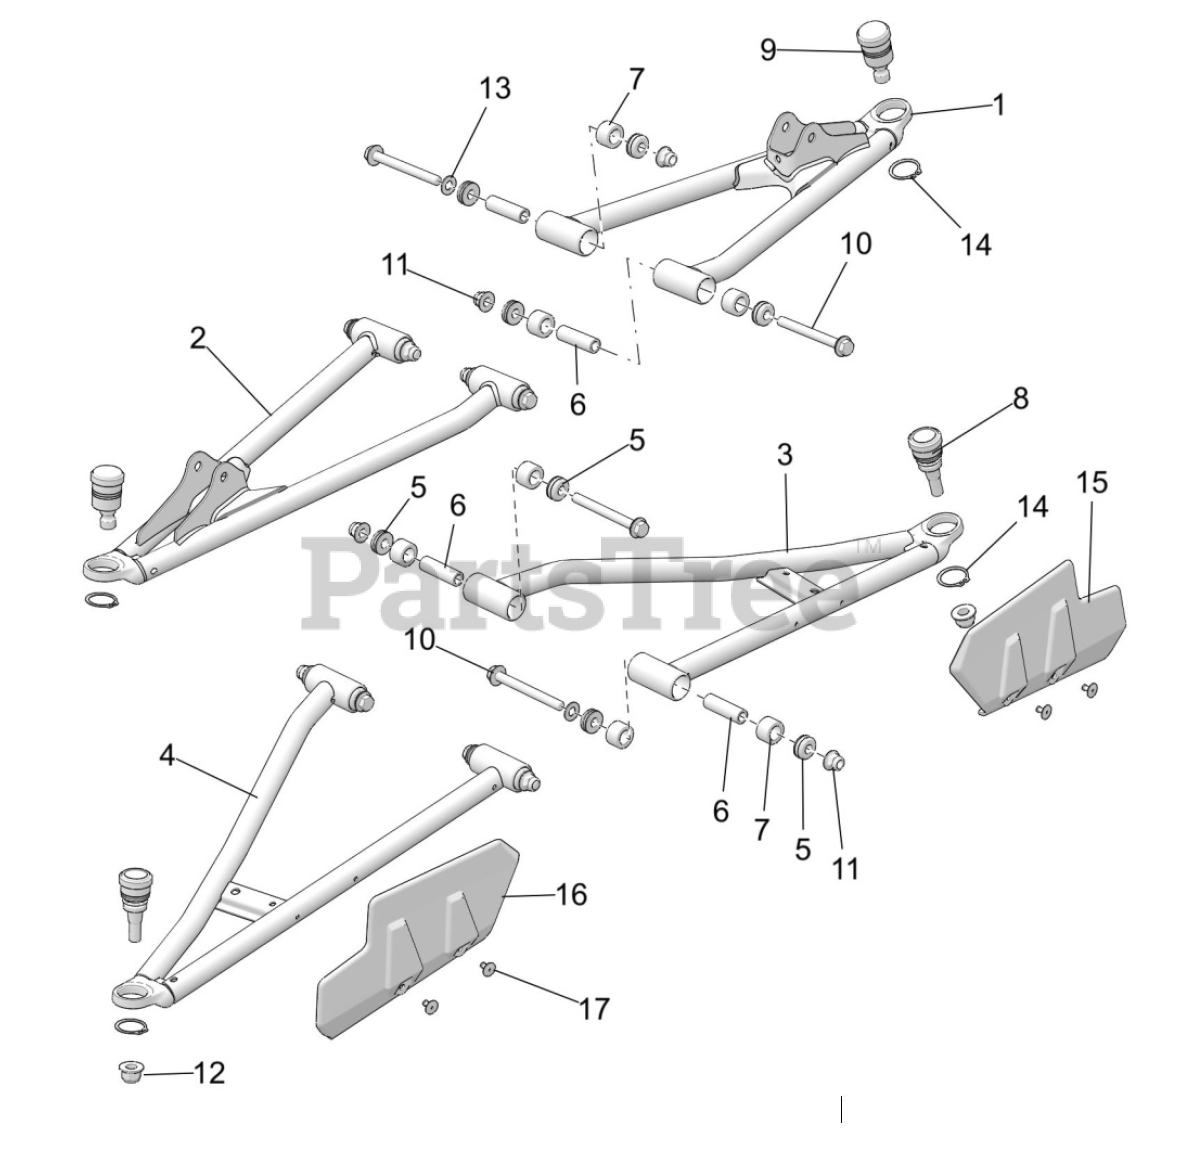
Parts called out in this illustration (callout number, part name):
1	WELD-A-ARM,FR,UPR,LH,BLK
2	WELD-A-ARM,FR,UPR,RH,BLK
3	WELD-A-ARM,FRT,LWR,LH,M.BLK
4	WELD-A-ARM,FRT,LWR,RH,M.BLK
5	ASM-PIVOT CAP,SEALED,M10
6	SHAFT-PIVOT,SHORT,M10
7	BUSHING-STANDARD,SUSP,M10
8	BALL-JOINT,M12X1.50,TAPERED
9	BALL-JOINT,10MM STUD
10	SCR-HXFL-M10X1.25X95 10.9 ZOD
11	NUT-M10X1.25,FLG,NYLOC-OLIVE D
12	NUT-M12X1.5,FLG,NYLOC-OLIVE D
13	WASHER,3/8 FW
14	RING-RETAINER,EXTERNAL,1.188
15	SHIELD-CV,FRONT,LH,BLK
16	SHIELD-CV,FRONT,RH,BLK
17	RIVET(50) *
